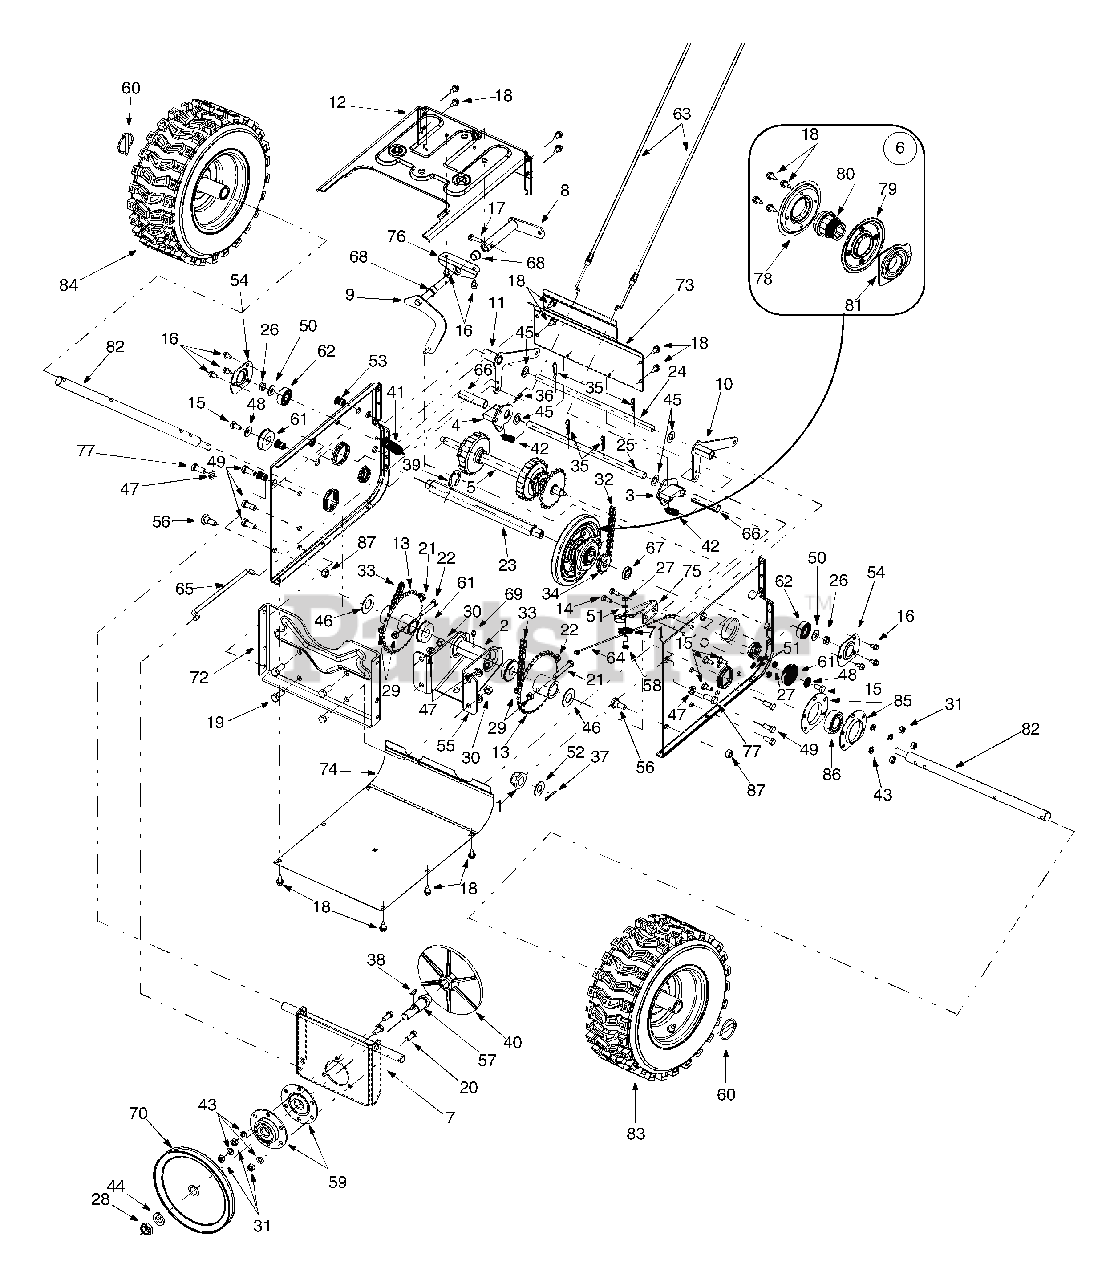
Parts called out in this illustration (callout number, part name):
1	Hex Flange Bearing
2	Spacer,.6725 x 1.125 x 2.485
3	Dogg Assembly LH
4	Dogg Assembly RH
5	Drive Shaft Assembly
6	Friction Wheel Assembly
9	Shift Rod Assembly
10	Auger Actuator Bracket Assy.
14	Hex Screw, 1/4-28 x.625"
15	Hex Screw, 5/16-18 x.625"
16	Self-tapping Screw, 1/4-20 x.5
17	Self-tapping Screw, 1/4-20 x 1"
18	Self-tapping Screw, 1/4-14 x.625"
19	Hex Screw 3/8-16 x .880"
20	Hex Screw 5/16-18 x .75"
21	Hex Screw 5/16-18 x 2"
22	Hex Screw 5/16-18 x 1.75"
23	Hex Drive Shaft
24	Actuator Shaft
25	Actuator Drive Shaft
27	Hex Nut 1/4-28
28	Jam Lock Nut
29	Flange Lock Nut, 5/16-18
30	Hex Nut 3/8-16
31	Hex Nut 5/16-18
34	Sprocket, 10T
35	Hairpin Clip
36	Hairpin Clip
37	Cotter Pin
38	Key
39	Retainer Ring
40	Drive Plate
41	Extension Spring
42	Extension Spring
43	Lock Washer 5/16
44	Lock Washer 5/8
45	Flat Washer
46	Flat Washer
47	Lock Washer
48	Bell Washer
49	Self-tapping Screw, 5/16-12 x.750
50	Flat Washer
51	Lock Washer
52	Flat Washer
53	Nut Insert, 3/8-16
54	Bearing Retainer Bracket
56	Shoulder Screw
57	Drive Plate Spindle
58	Shoulder Screw 1/4-28 x .375"
59	Bearing Housing Assembly
61	Ball Bearing
62	Ball Bearing
63	Steer Cable
64	Auger Idler Cable
65	Drive Clutch Rod
66	Split Spacer
67	Spacer
68	Flange Bearing
69	Lube Fitting, 3/16
70	Drive Pulley
71	Roller Cable
78	Bonded Friction Wheel
79	Friction Wheel Plate
80	Friction Wheel Hub
81	Friction Wheel Bearing Assembly
82	Wheel Axle
83	Wheel Assembly, LH
85	Bearing Housing
86	Self Aligning Bearing
87	Flange Lock Nut, 3/8-16
